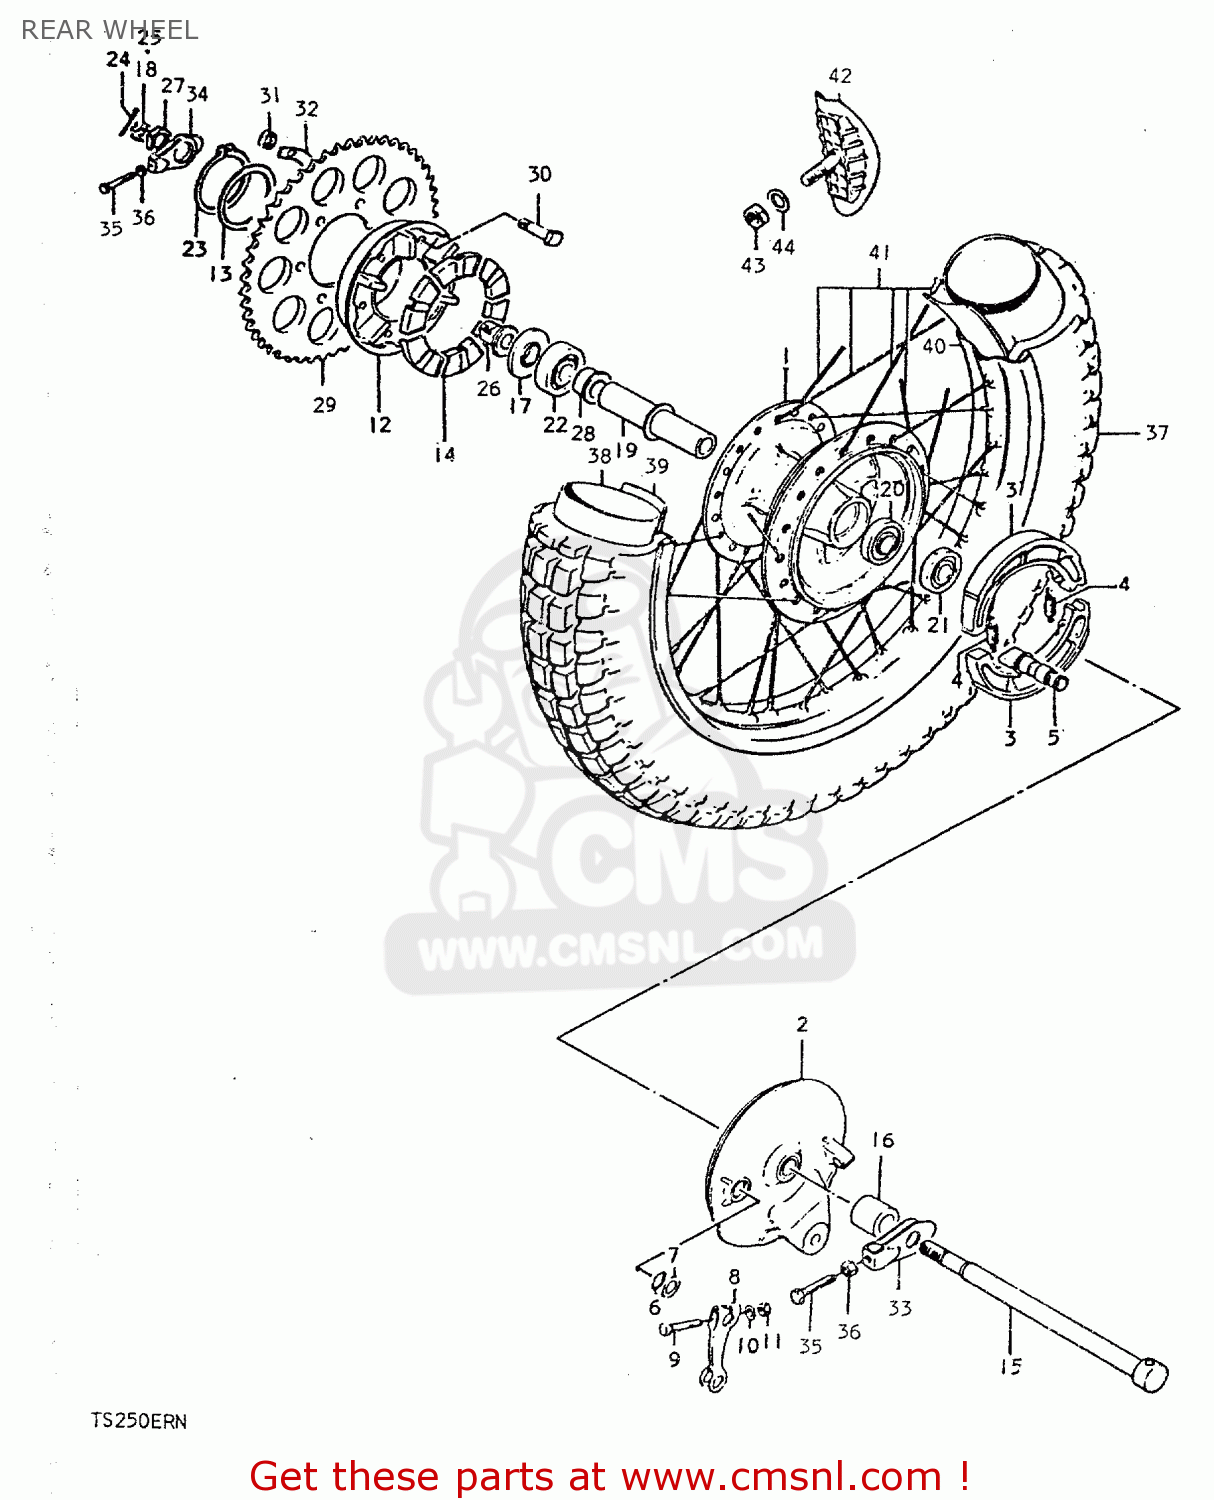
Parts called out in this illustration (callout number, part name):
1	DRUM,REAR HUB
2	PANEL,REAR HUB
3	SHOE,BRAKE (MCA)
4	SPRING
5	CAM,FRONT BRAKE
6	O-RING,BOSS
7	WASHER (15X24X1.6)
8	LEVER,REAR BRAKE CAM
9	BOLT 6X40
10	WASHER
11	NUT
12	DRUM,REAR SPROCKET MOUNT
13	WASHER(62.5X77X1.6)
14	ABSORBER,RR WHEEL HUB SHOCK
15	AXLE,REAR
16	SPACER (15.2X26X20)
17	SPACER,REAR AXLE,RIGHT
18	NUT
19	SPACER,REAR HUB BEARING
20	BEARING, RH
21	OIL SEAL
22	BEARING
23	CIRCLIP
24	PIN 30X40
26	SPACER,REAR AXLE,LEFT
27	NUT
28	SPACER,REAR HUB BEARING
29	SPROCKET,REAR
30	BOLT(8X33.5)
31	NUT
32	WASHER
33	ADJUSTER,CHAIN
34	ADJUSTER,CHAIN,L
35	BOLT
36	NUT
37	TIRE
38	TUBE,INNER
39	PROTECTOR,WHEEL,INNER
40	RIM,REAR WHEEL (2.15X18)
41	SPOKE SET,REAR
42	STOPPER,BEAD
43	NUT
44	WASHER
